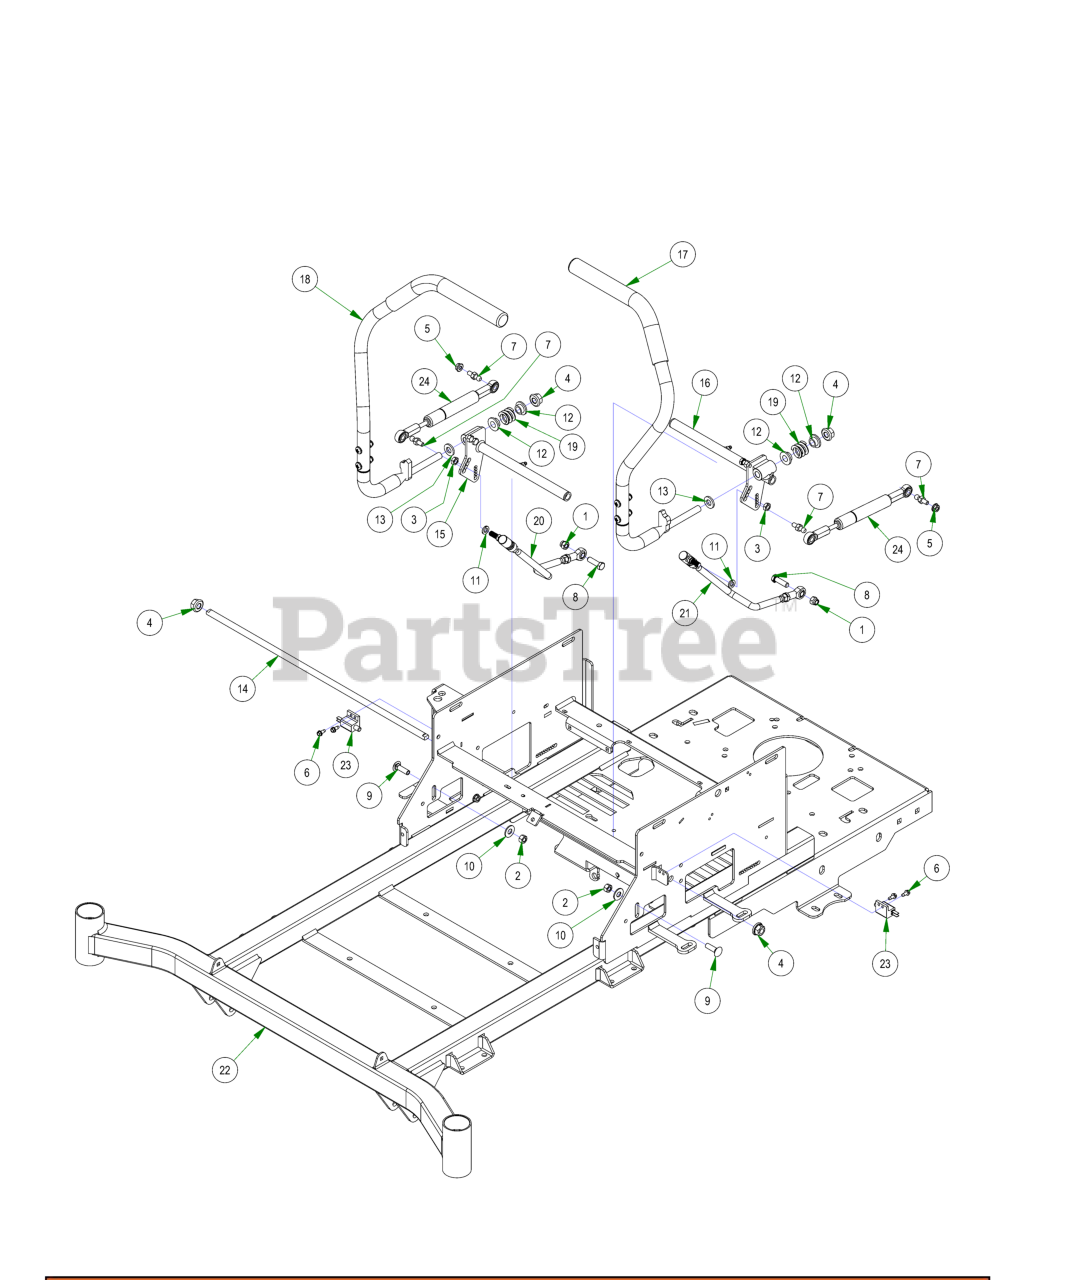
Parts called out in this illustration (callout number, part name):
1	3/8-16 NYLON INSERT LOCKNUT ZINC
2	3/8-16 HEX NUT ZINC
3	3/8-24 HEX NUT ZINC YELLOW
4	1/2-13 NYLON INSERT FLANGE LOCKNUT ZINC
5	5/16-18 HEX SERRATED FLANGE NUT HARD/ZINC
6	12-24 X 1/2 HEX WASHER UNLSOT F TCS ZINC
7	10mm Damper Ball Stud-Steering
8	3/8-16 X 1-1/4 HEX CAP SCREW (GR.5) ZINC
9	3/8-16 X 1-1/4 CARRIAGE BOLT ZINC
10	3/8 FLAT WASHER USS (1" OD) ZINC
11	3/8 SPLIT LOCKWASHER ZINC
12	.525 ID SHOULDER WASHER NYLON
13	.505 ID X 1.000 OD X .125 THICK FLAT WASHER NYLON
14	2021 Maverick Steering Actuator Rod
15	2021 Maverick Drive Arm Actuator RH Assembly
16	2021 Maverick Drive Arm Actuator LH Assembly
17	ZT Steering Arm-Left
18	ZT Steering Arm-Right
19	Drive Lever Spring
20	Push Rod-Right
21	Push Rod-Left
22	2024 MZ-Avenger 54-60 Frame
23	Safety Switch
24	ZT Avenger Steering Dampener
